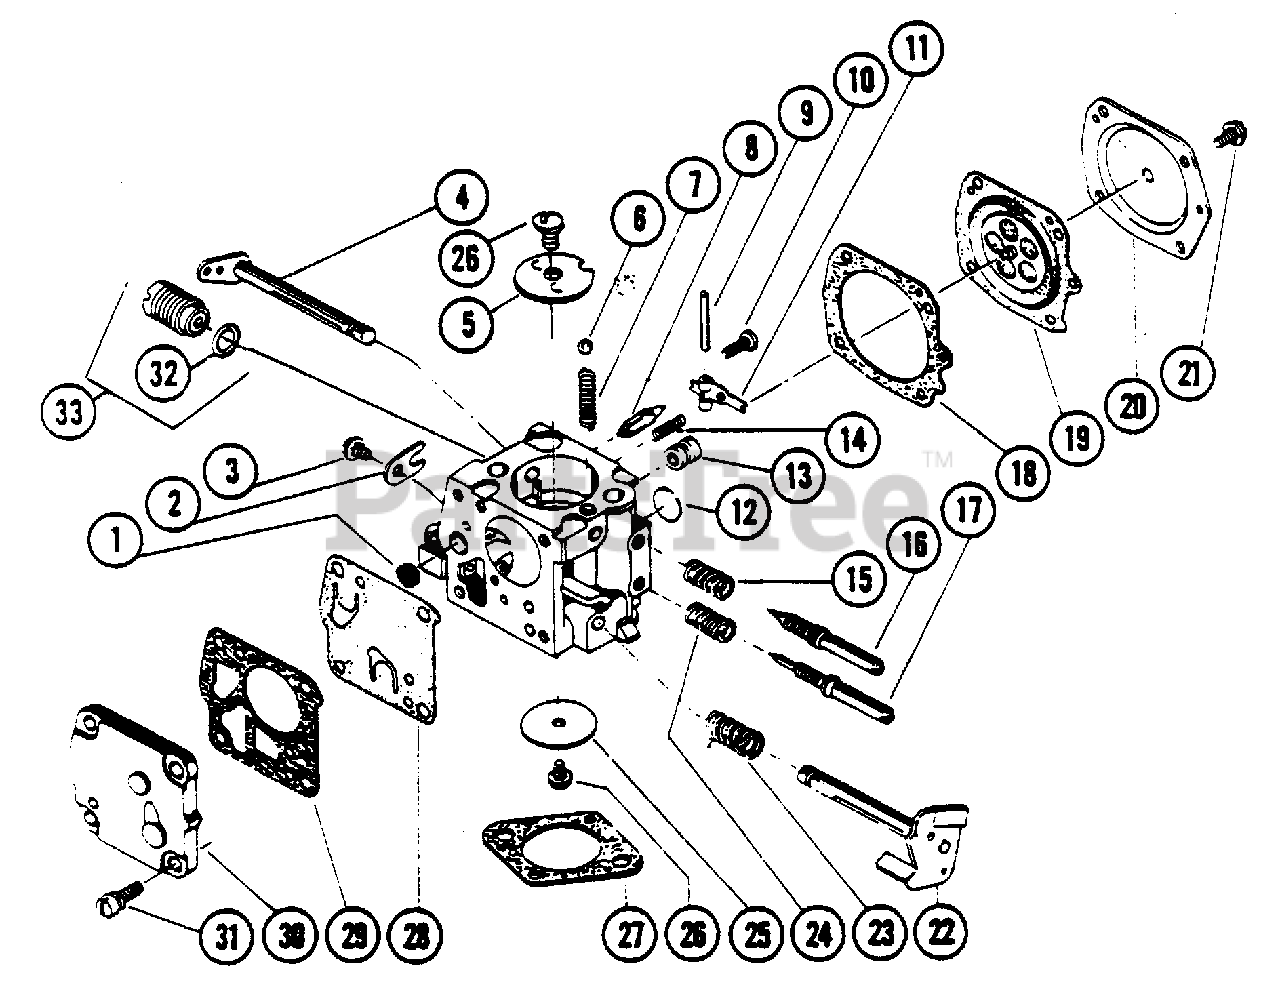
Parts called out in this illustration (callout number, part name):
1	Inlet Screen
2	Throttle Shaft Clip
3	Throttle Shaft Clip Ret. Screw
4	Choke Shaft & Lever
5	Choke Shutter
6	Choke Friction Ball
7	Choke Friction Spring
8	Inlet Needle
9	Inlet Pinion Pin
10	Inlet Pinion Pin Ret. Screw
11	Inlet Control Lever
12	Body Channel Welch Plug (Large)
13	Nozzle Check Valve
14	Inlet Tension Spring
15	High Speed Mixture Screw Spring (Blue)
16	HIGH SPEED SCREW
17	Idle Mixture Screw
18	Diaphragm Gasket
19	Diaphragm
20	Diaphragm Cover (Dana part number)
21	Diaphragm Cover Screw & Lockwasher (4)
22	Throttle Shaft & Lever
23	Throttle Shaft Return Spring
24	Idle Mixture Screw Spring (Yellow)
25	Throttle Shutter
26	Shutter Screw & Lockwasher
28	Fuel Pump Diaphragm
29	Fuel Pump Gasket
30	Fuel Pump Cover
31	Fuel Pump Cover Ret. Screw & Lockwasher (4)
32	Gov. Valve Gasket - (5200 only)
33	Governor Valve Ass'y - (5200 only)
